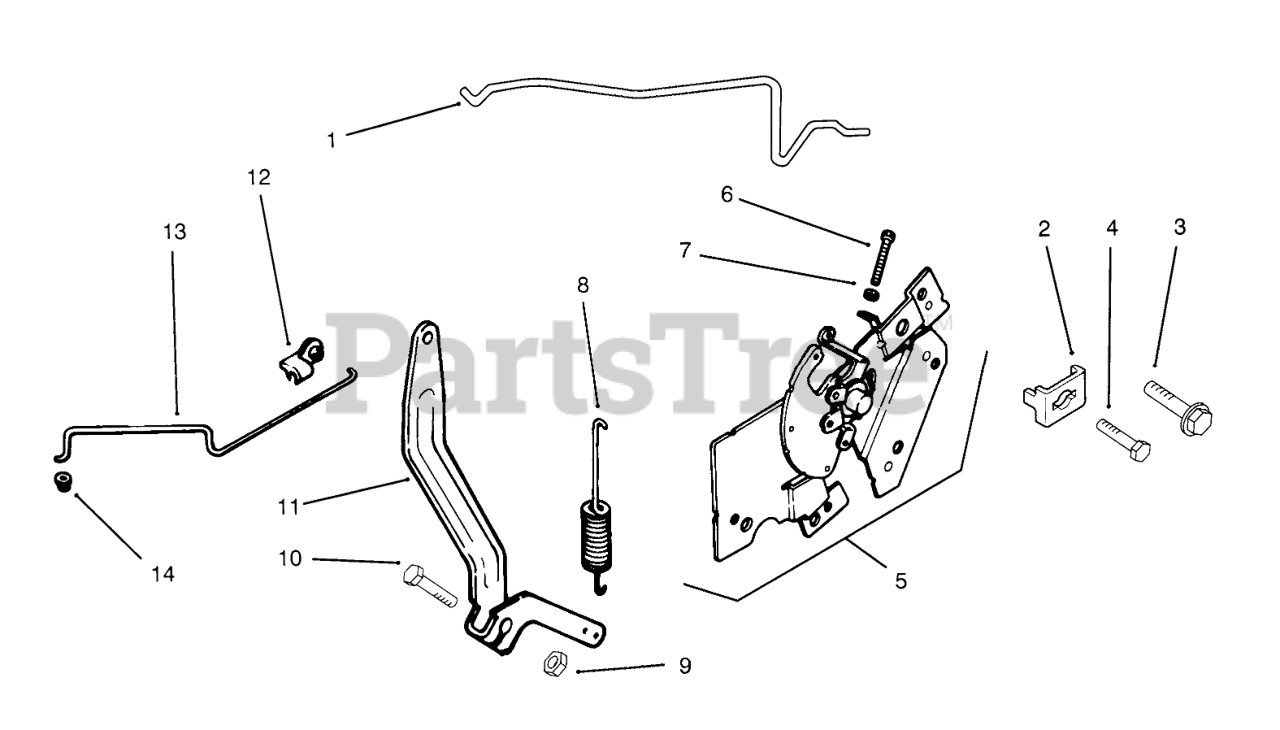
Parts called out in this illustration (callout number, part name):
1	Linkage-Choke (Only On: 72042,72043,72062,72063)
2	Clamp-Cable (Only On: 72042,72043,72062,72063)
3	Screw-HH M6x1.0x16 (Only On: 72042,72043,72062,72063)
4	Screw M5x0.8x16 (Only On: 72042,72043,72062,72063)
5	Control-ASM INCL 6-7 (Only On: 72042,72043,72062,72063)
6	Screw-HHF M4x0.7x28 (Only On: 72042,72043,72062,72063)
7	Nut-Hex M4x0.7 (Only On: 72042,72043,72062,72063)
8	Spring-Governor (Only On: 72042,72043,72062,72063)
9	Nut M6x1.0 (Only On: 72042,72043,72062,72063)
10	Screw M6x1.0x25 (Only On: 72042,72043,72062,72063)
11	Lever-Governor (Only On: 72042,72043,72062,72063)
12	Bushing-Linkage (Only On: 72042,72043,72062,72063)
13	Linkage-Throttle (Only On: 72042,72043,72062,72063)
14	Bushing-Linkage (Only On: 72042,72043,72062,72063)
